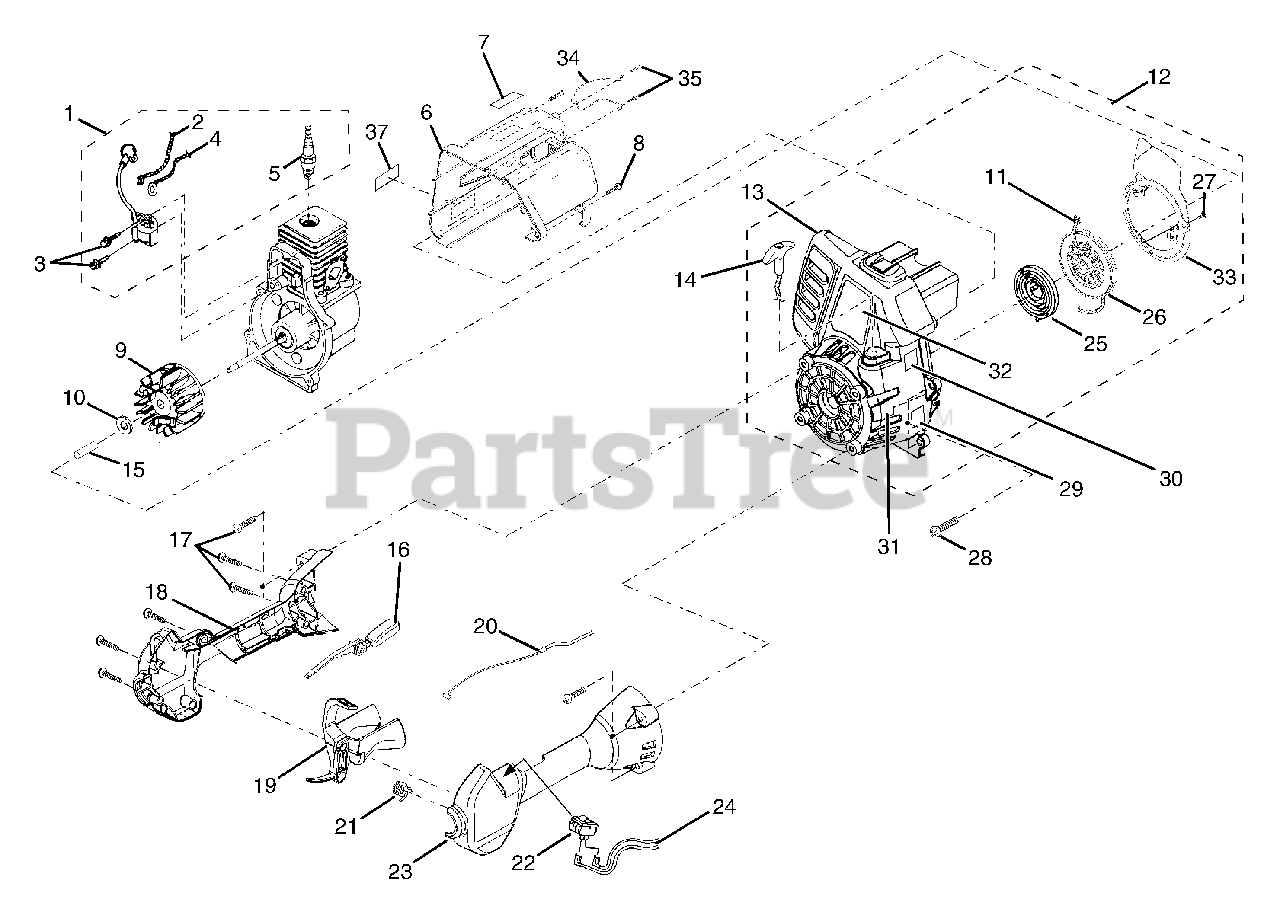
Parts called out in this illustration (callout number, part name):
1	IGNITION KIT.
2	ELECTRICAL LEAD
4	ELECTRICAL LEAD
5	SPARK PLUG
6	REAR COVER ASSEMBLY
7	LOGO PLATE
9	ROTOR AND PAWL ASSEMBLY
11	STARTER ROPE 42 in.
12	STARTER ASSEMBLY
13	STARTER HOUSING AND EYELET
14	ERGO GRIP
15	DRIVE CONNECTOR
16	INTERLOCK TRIGGER
18	CONTROL HANDLE / RH
20	THROTTLE CABLE
22	SWITCH
23	CONTROL HANDLE / LH
24	ELECTRICAL LEADS
25	SPRING & CONTAINER
26	STARTER PULLEY
29	DECAL, 113 POWER SOUND
30	DECAL, ZIP START
31	DECAL, CE
32	DECAL, MODEL
33	AIR BAFFLE PLATE
34	MUFFLER GUARD
37	FUEL MIX RATIO DECAL
